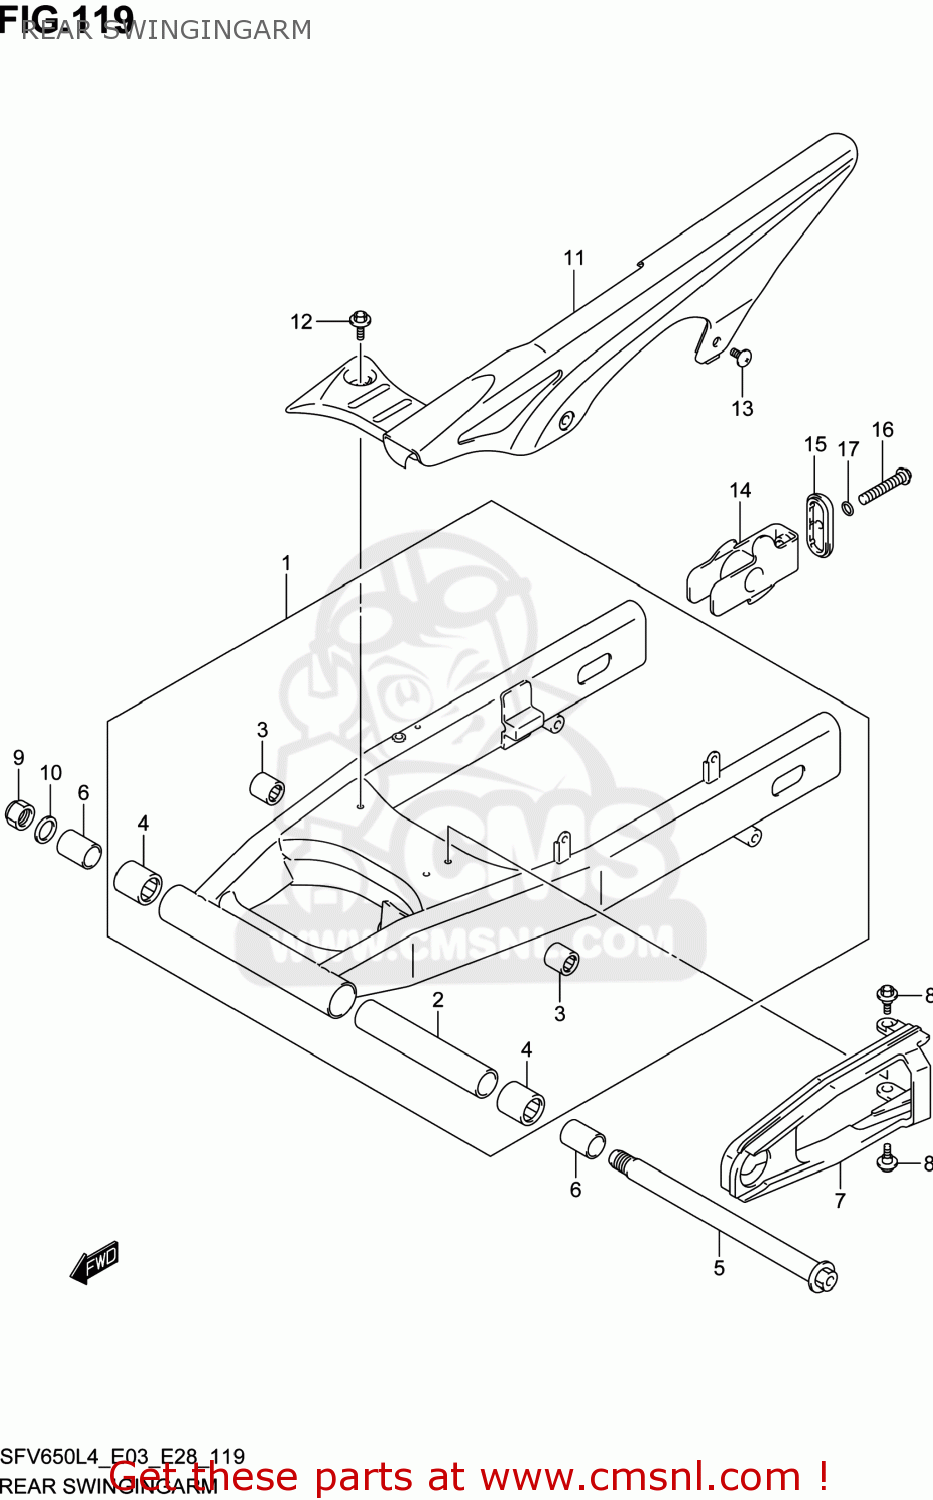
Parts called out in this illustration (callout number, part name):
1	SWINGINGARM ASSY,RR
2	SPACER,RR SWGARM PIVOT CTR
3	BEARING(17X24X25)
4	BEARING(25X33X35)
5	SHAFT,RR SWINGINGARM PIVOT
6	SPACER,RR SWGARM PIVOT
7	BUFFER,CHAIN TOUCH DEFENSE
8	BOLT(6X17.8)
9	NUT
10	WASHER(18.5X28X2.6)
11	CASE,CHAIN
12	BOLT(6X16)
13	SCREW(6X16)
14	ADJUSTER,CHAIN
15	PLATE,CHAIN ADJUSTER GUIDE
16	BOLT(8X50)
17	WASHER
